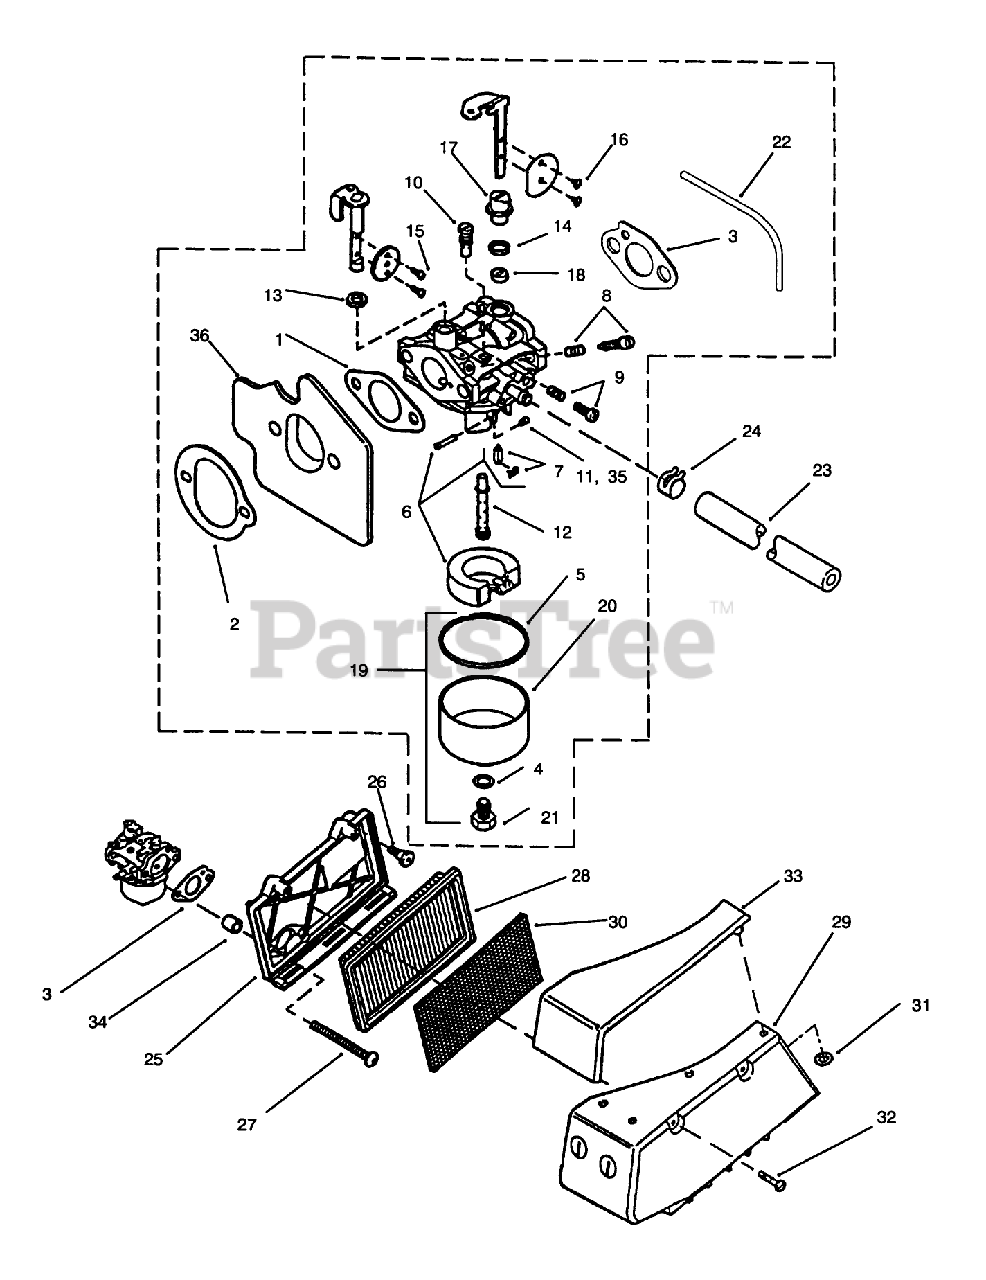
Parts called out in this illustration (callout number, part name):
1	GASKET SM
2	GASKET SM
3	GASKET-FIL SM
4	GASKET-BOWL RET S
5	GASKET-FUELBOWL S
7	NEEDLE & CLIP S
10	PILOT JET
11	CARB JET
14	SEAL CHOKE SHAFT
16	SCREW CHOKE VALVE
21	SCREW,BOWL RET S
22	HOSE-CARB.VENT SM
23	GAS LINE SM
24	HOSE CLAMP SM
28	ELEMENT-AIR SM
29	AIR FILTER COVER
31	NUT-PUSH
35	MAIN JET
36	SPACER & NOZZ SM
